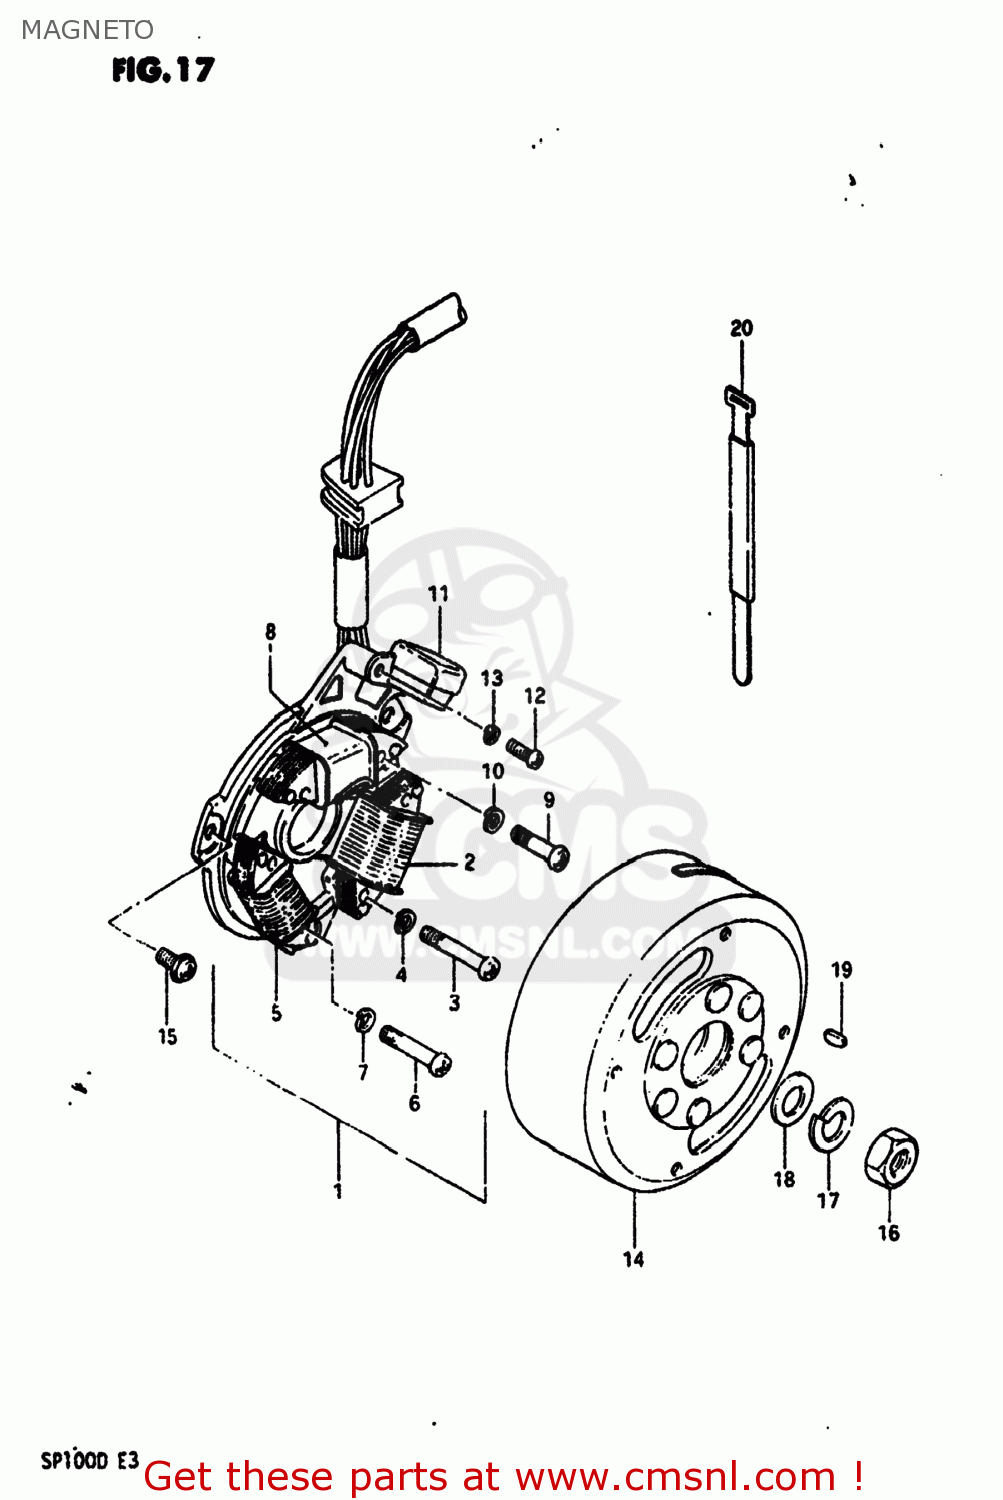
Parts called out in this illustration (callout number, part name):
1	STATOR ASSEMBLY
2	COIL,LIGHTING
3	SCREW
4	LOCK WASHER
5	COIL,CHARGING
6	SCREW
7	LOCK WASHER
8	COIL,IGNITION PRIMARY
9	SCREW
10	LOCK WASHER
11	COIL
12	SCREW
13	LOCK WASHER
14	ROTOR,FLYWHEEL
15	SCREW(5X14)
16	NUT (10MM)
17	LOCK WASHER
18	WASHER
19	KEY
20	CLAMP L:110
